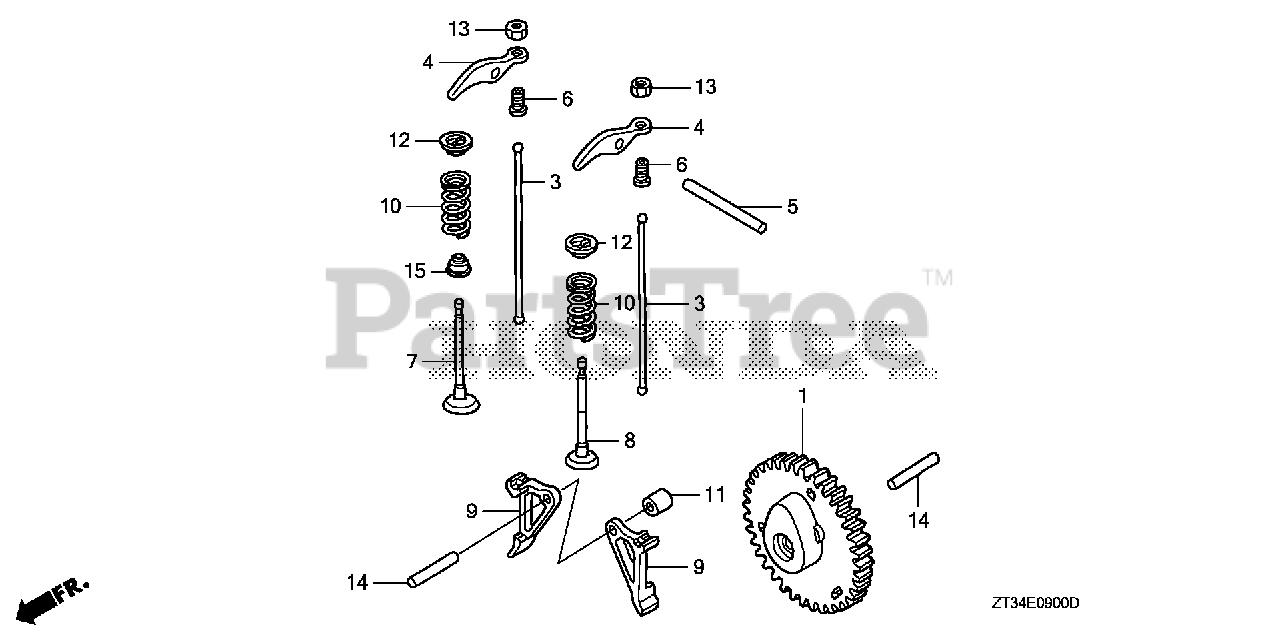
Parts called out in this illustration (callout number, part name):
1	CAMSHAFT ASSY.
4	ARM, VALVE ROCKER
5	ROLLER (4X37.8)
6	PIVOT, ROCKER ARM
7	VALVE, IN.
8	VALVE, EX.
9	LIFTER, VALVE
10	SPRING, VALVE
11	COLLAR, LIFTER
12	RETAINER, VALVE SPRING
13	NUT, TAPPET ADJUSTING
14	ROLLER (5X29.8)
15	SEAL, VALVE STEM
